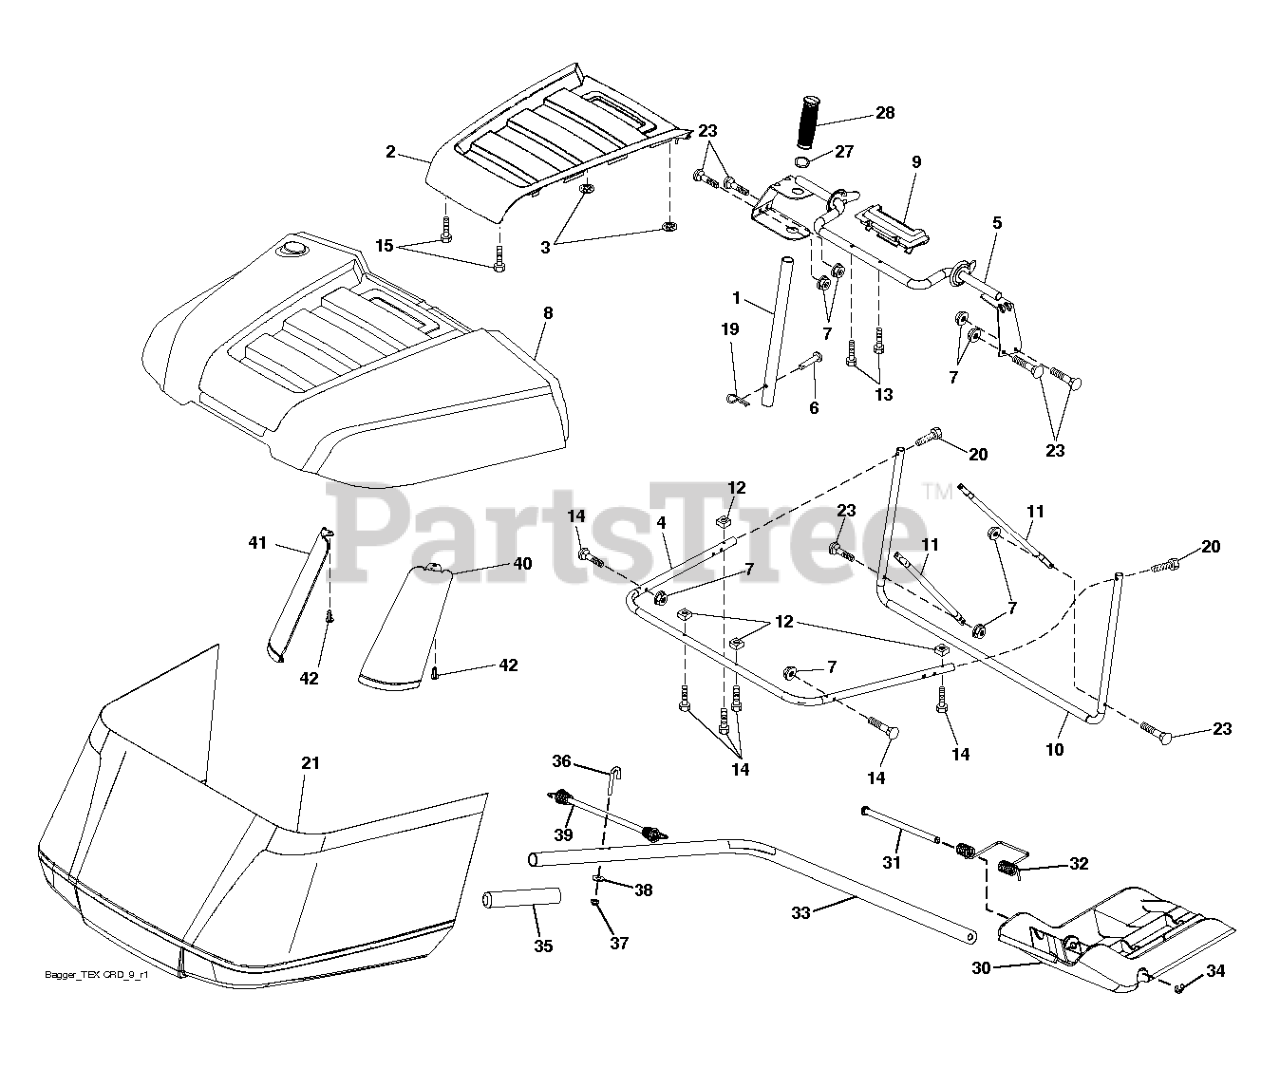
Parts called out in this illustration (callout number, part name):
1	TUBE.HANDLE.BAGGER.CRD/SRD.BLA
2	APPLIQUE.TOP.BAG.SRD.ORANGE
3	NUT.PUSH.156
4	SUBASM.TOP.TUBE.TEX.CRD
5	FRAME.ASM.TOP.BAGGER.SRD
6	RIVET,DRILLED
7	NUT T
8	BAGGER.TOP.SUB.ASSEM.SRD
9	INSERT.HANDLE.BAGGER.(2 2)
10	FRAME.FRONT.SRD.BAGGER
11	NUT.SQUARE.1/4
12	NUT.SQUARE.1/4
13	SCREW.1/4X1.150.HXWSH
14	BOLT.SHOULDER.HX.WSH.1/4X1.150
15	SCREW,#8.FLAT.HEAD.DRILL.TIP
19	PIN.COTTER.5/16.BOW TI
20	SCREW.HEXCAP.1/4-20X1.375(2 2)
21	BAGGER.TOP.SRD.APPLIQUE
27	RB GROMMET.RUBBER.SRD
28	GRIP.HANDLE.BLACK
30	PLUG PLUG
31	PIN PIN.HINGE
32	SPRING SPRING DOUBLE TORSION
33	SHAFT SHAFT TEX CRD MULCH PLU
34	E-RING.5/16"
35	GRIP GRIP MULCH PLUG HAND
36	BOLT BOLT J
39	BUBGEE BUBGEE TEX CRD
42	CLIP CHRISTMAS TREE CLIP
